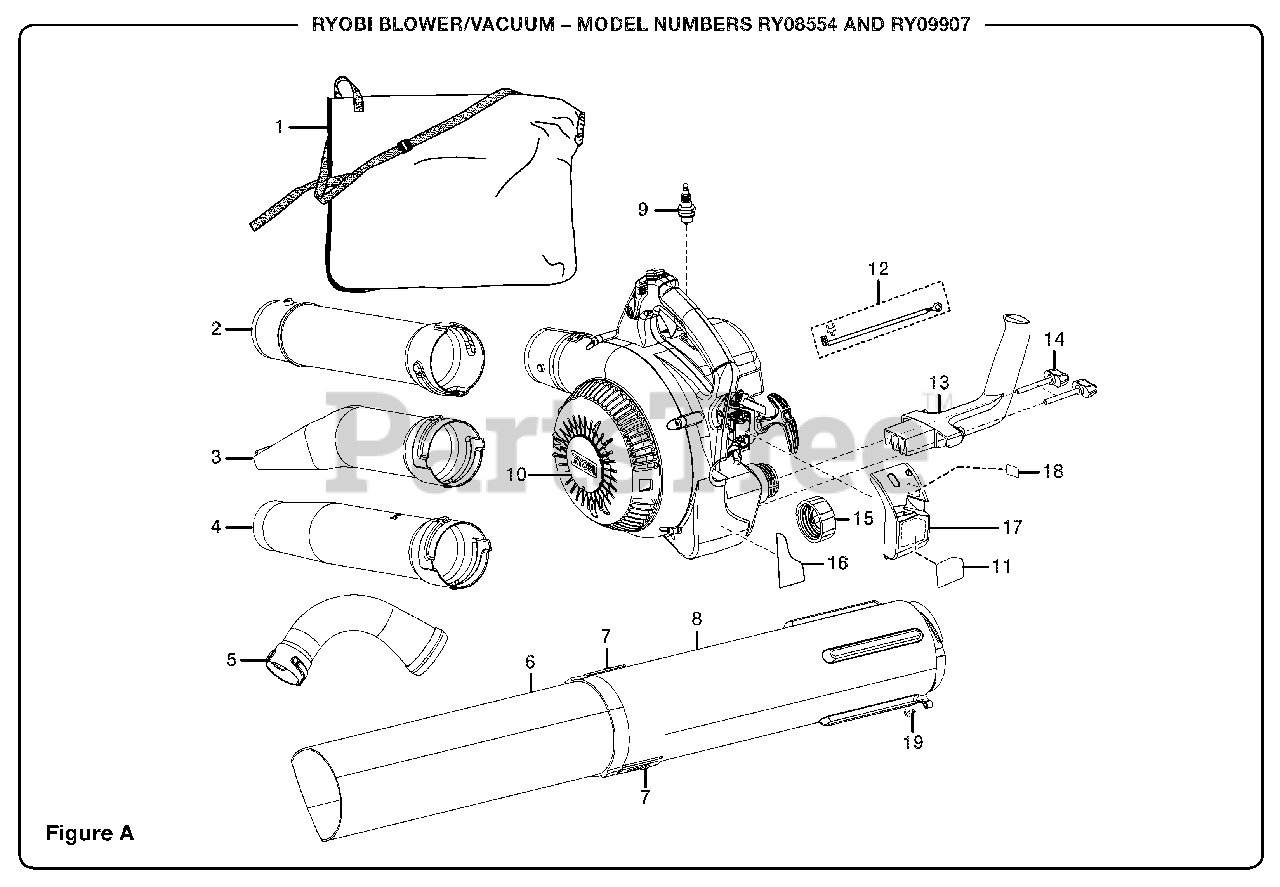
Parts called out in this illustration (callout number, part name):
1	Vacuum Bag w/Shoulder Strap
2	Upper Blower Tube
3	High Velocity Nozzle w/ Leaf Scraper
4	Sweeper Nozzle
5	Vacuum Bag Adaptor
6	Lower Vacuum Tube
7	Vacuum Tube Screw (10-14 x 1/2 in.)
8	Upper Vacuum Tube
9	Spark Plug
10	Vacuum Door Label
11	Starting Label
12	Ground Wire Kit
13	Vacuum Handle
14	Vacuum Handle Knob
15	Fuel Cap Assembly
16	Warning Label
17	Air Filter Cover
18	Choke Label
19	Screw (M5 x 14 mm)
